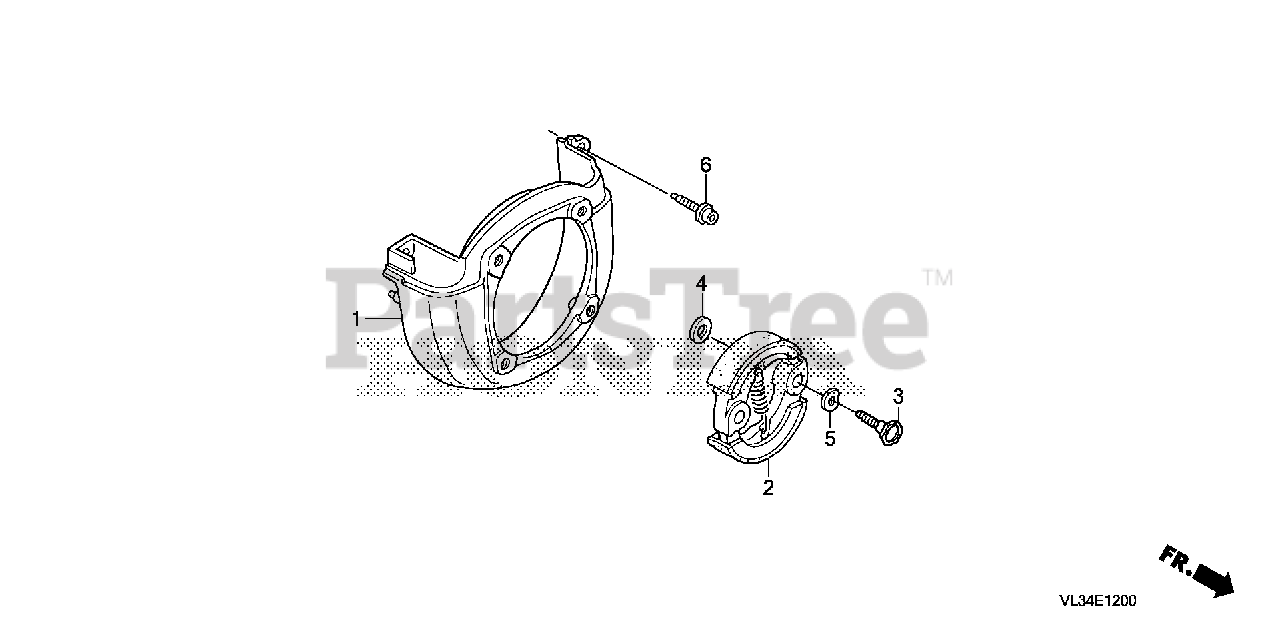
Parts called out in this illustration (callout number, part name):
1	COVER, FAN
2	CLUTCH ASSY. (ACRO)
3	BOLT, CLUTCH (8MM)
4	WASHER, CLUTCH (8X17)
5	WASHER, WAVE (10MM)
6	BOLT, SOCKET (5X20)
